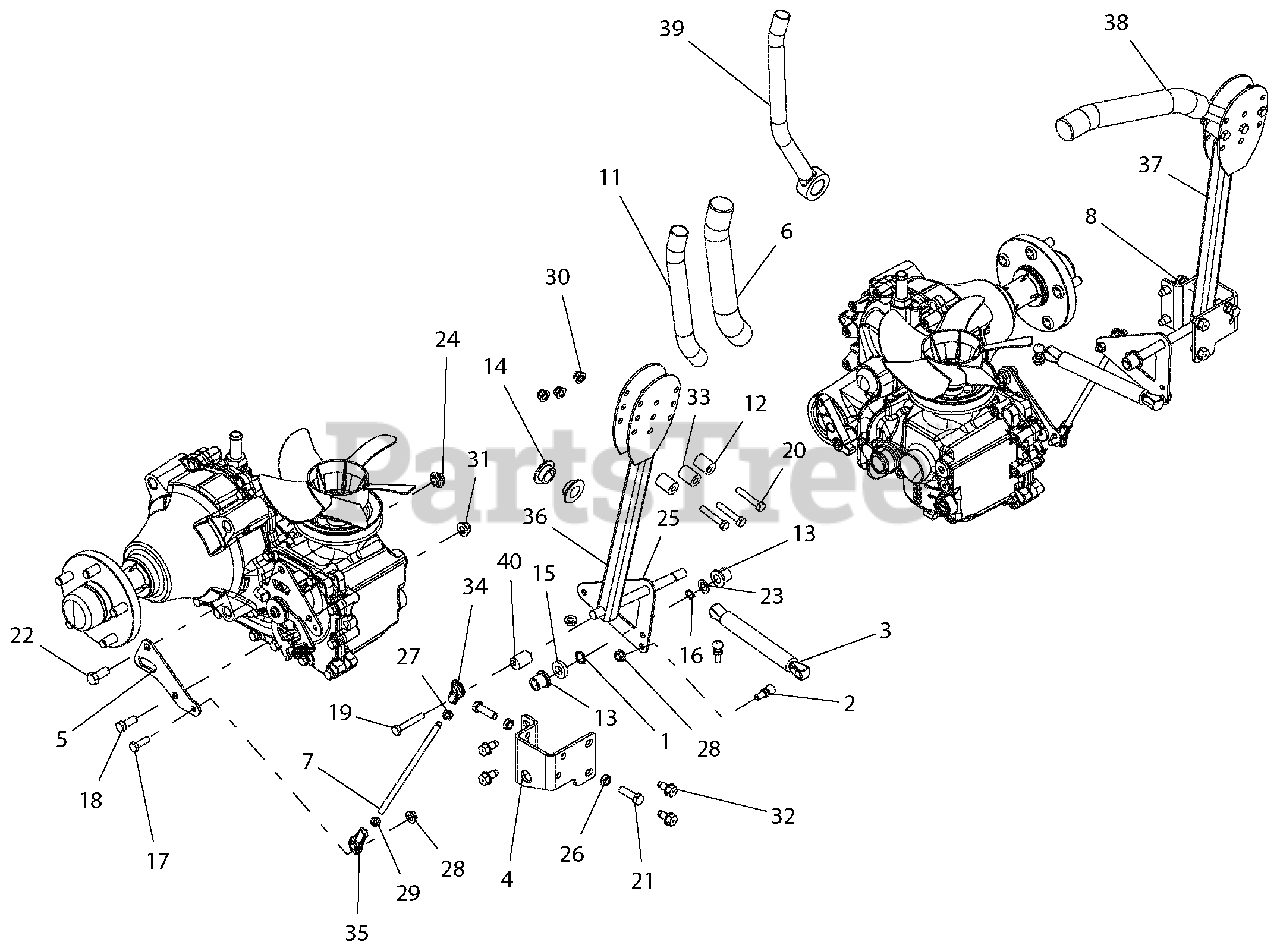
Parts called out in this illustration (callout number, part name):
1	WAVE WASHER .531X.781X.125 FH
2	STUD-BALL
3	DAMPER,
4	BRKT, RH CONTROL STOP
5	BRKT., CONTROL MTG-BLACK
6	GRIP, HANDLEBAR
7	ROD, STEERING
8	BRKT, LH CONTROL STOP
11	TUBE, .88ID X 1.00OD X 10.25
12	BSHG, ECCENTRIC .328 X .750 X .970
13	BSHG, FLANGE .515 X .750 X .745 X 1.00 NYLON
14	BSHG, FLANGE .762 X 1.48 X .44 NYLON
16	RG-RTNG-EXT .500x.050
17	BLT-HEX .31-18X1.00 GR5 YWZC
18	BLT-HEX .38-16X1.00 GR5 YWZC
19	BLT-HEX .31-18X2.00 GR5 YWZC
20	BLT-HEX .31-18X1.75 GR5 YWZC
21	BLT-HEX .38-16X1.25 GR5 YWZC
22	BLT-HEX .44-14X1.00 GR5 YWZC
23	WSHR-FL-STL .520X.810X.033 YWZC
24	NUT-LK-NYL-FLG .44-14 YWZC
25	NUT-LK-CTR .31-18 YWZC
26	NUT, JAM .375-16 YWZC
27	NUT-JAM
28	NUT, LK-TOP-FLG .312-18 YWZC
29	NUT, JAM -LH .31-24 YWZC
30	NUT-LK-NYL-FLG .31-18 YWZC
31	NUT-LK-NYL-FLG .38-16 YWZC
32	SCR-TAP .38-16X.75 HWH TR YWZ
33	SPACER, .328 X .76 X 1.01
34	ALIGNABALL, 5/16 RH THREAD
35	ALIGNABALL, 5/16 LH THREAD
36	WLDMT, RH CONTROL ARM
37	WLDMT, LH CONTROL ARM
38	WLDMT, LH HANDLE
39	WLDMT, RH HANDLE
40	ECCENTRIC
